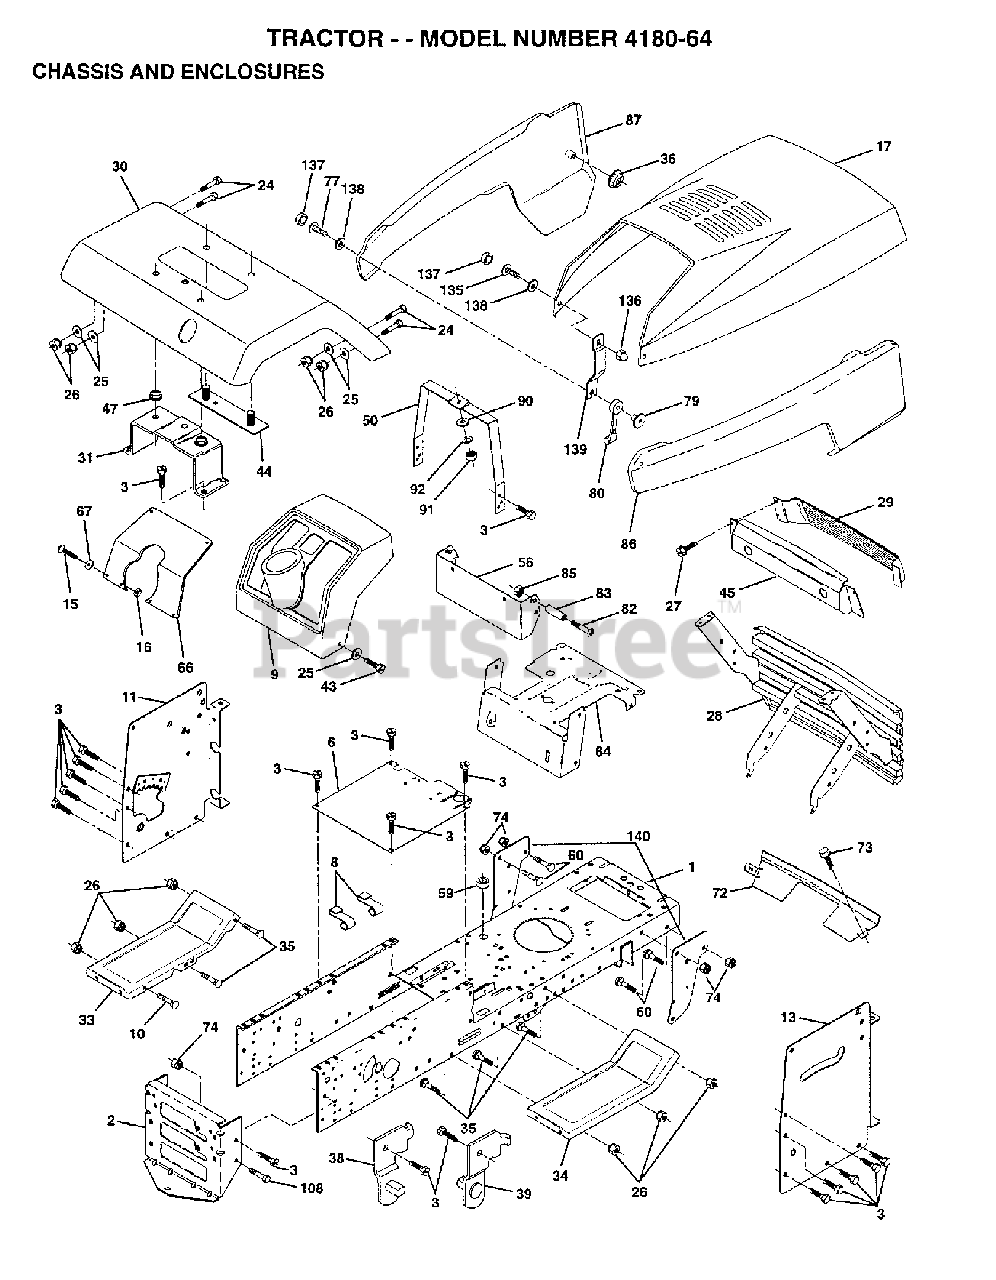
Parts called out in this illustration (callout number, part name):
1	CHASSIS WLD MT 11G
8	CLIP,INSULATOR
17	Poulan TBD
25	WASHER
26	NUT
30	Poulan TBD
31	FENDER BRKT
33	Poulan TBD
34	Poulan TBD
36	PAL NUT LT
38	BRACKET LH PIVOT
39	BRACKET RH PIVOT
44	STRAP-FENDER YT
47	NUT-PUSH YT
50	DASH SUPT YP
64	DASH LOWER LT
67	WASHER
72	Poulan TBD
73	SCREW CRT
74	LOCKNUT
77	SCREW
79	NUT.WELD
80	LATCH.HOOD.
82	SCREW
83	SPACER LT
85	NUT **
87	Poulan TBD
90	WASHER PM
91	NUT
92	LOCKWASHER
135	SCREW 10-24X3/8
136	NUT
137	SNAP CAP LT
138	WASHER LT
139	BRACKET.SUPPORT.HOOD/PANEL.NLA
